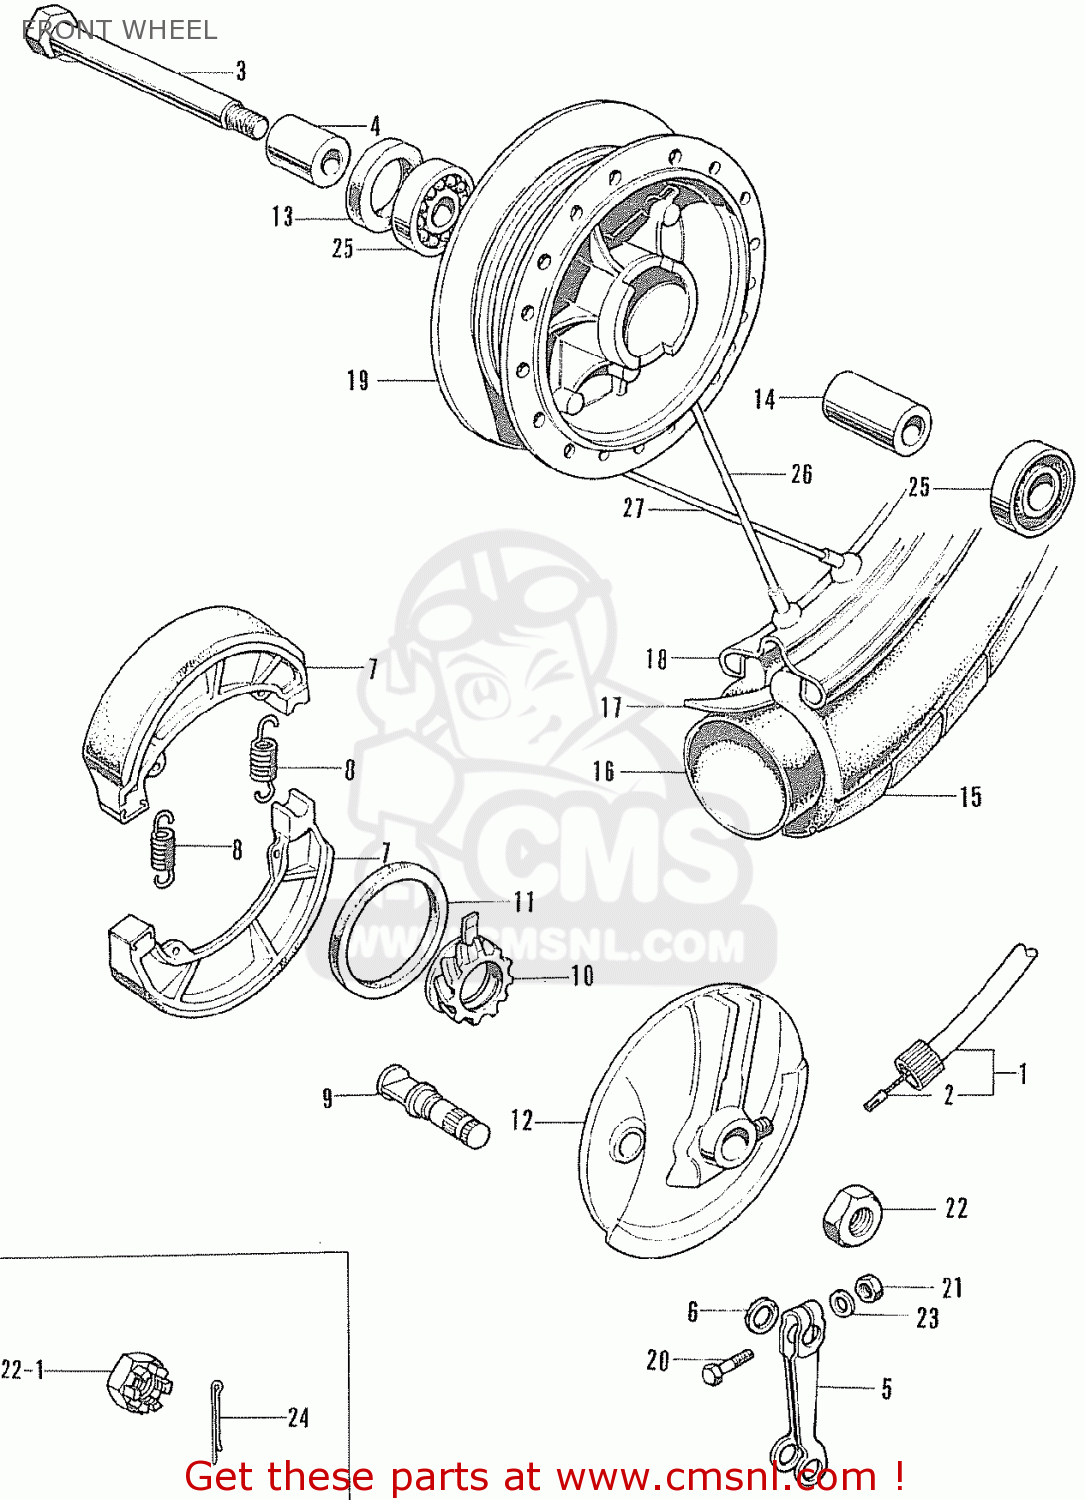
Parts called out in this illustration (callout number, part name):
1	CABLE,SPEEDOMETER
2	CABLE,INNER
3	AXLE,FRONT WHEEL
4	COLLAR,FRONT AXLE
5	ARM,FRONT BRAKE
6	DUST-SEAL, BRAKE
7	SHOE,FRONT BRAKE (MCA)
8	SPRING BRAKE SHOE
9	CAM,FRONT BRAKE
10	GEAR,SPEEDOMETER
11	OIL SEAL,54667
12	PANEL, FR. BRAKE
13	OIL SEAL 26427
14	COLLAR,FRONT AXLE
15	TIRE,FRONT 300-17
16	TUBE,300-17
17	FLAP,16-22
18	RIM,WHEEL
19	HUB,FRONT WHEEL
20	BOLT,HEX 6X20
21	NUT,HEX 6MM
22	NUT,HEX 14M/M
23	WASHER,PLAIN, 6MM
24	PIN,COTTER 3.0MM
25	B/BRG RAD N/COM
26	SPOKE,A 11X152
27	SPOKE, A#11X151.5
